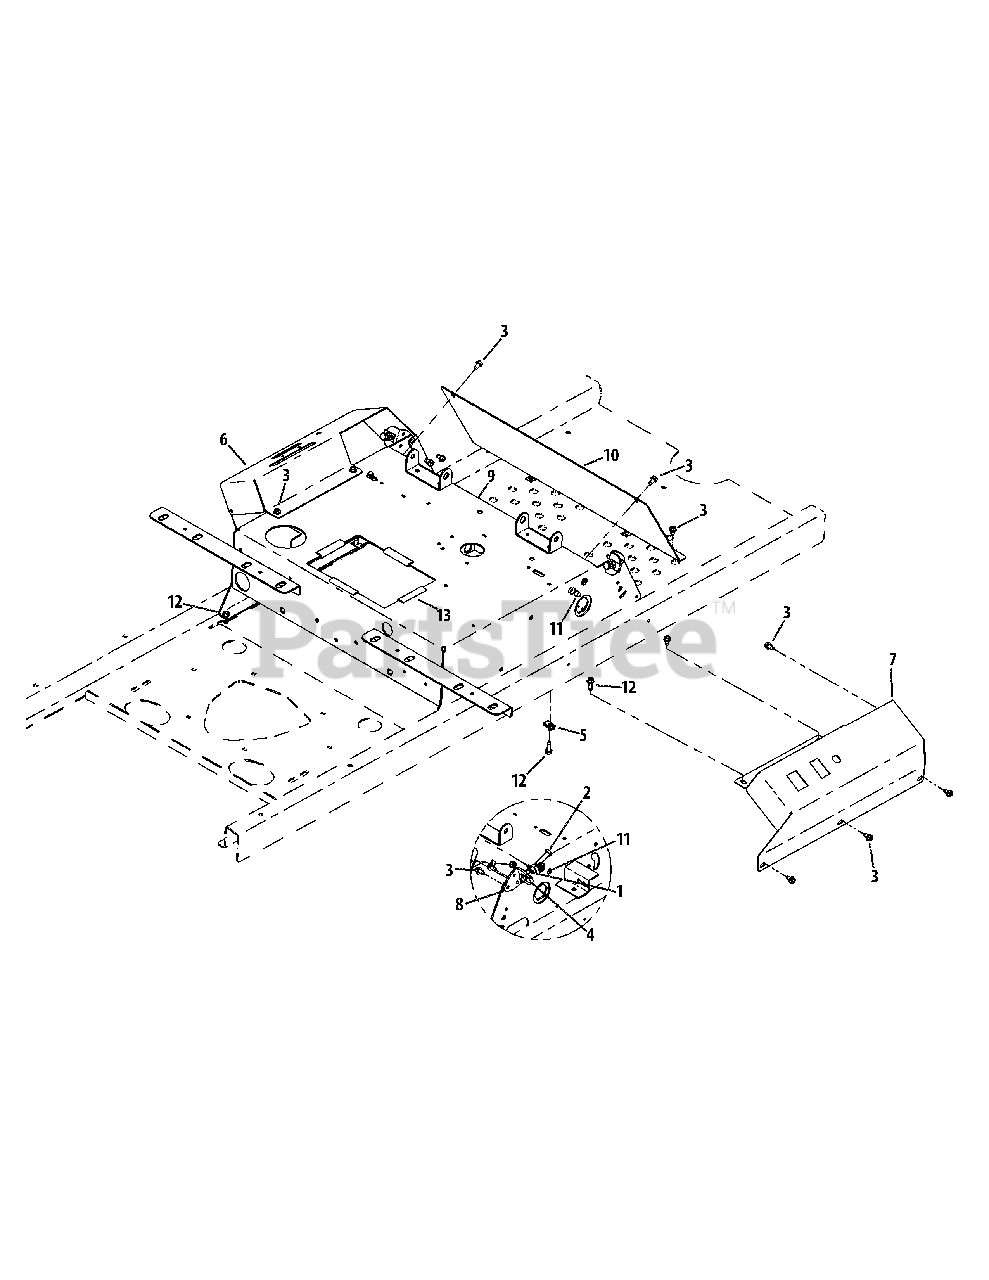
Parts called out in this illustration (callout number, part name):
1	Hex Nut, 5.16-18
2	HHCS, 5.16-18 x 1-1.4
3	Screw, 1.4-20 x 1/2
4	U-Nut, 5.16-18
5	U-Nut, 1.4-20
6	Left Hand Control Console
7	Right Hand Control Console
8	Forward/Reverse Stop Bracket
9	Control Housing Weldment
11	Self-Tapping Screw 5.16-18 x .750
12	Self-Tapping Screw, 1.4-20 x .75
13	Battery Edge Trim
